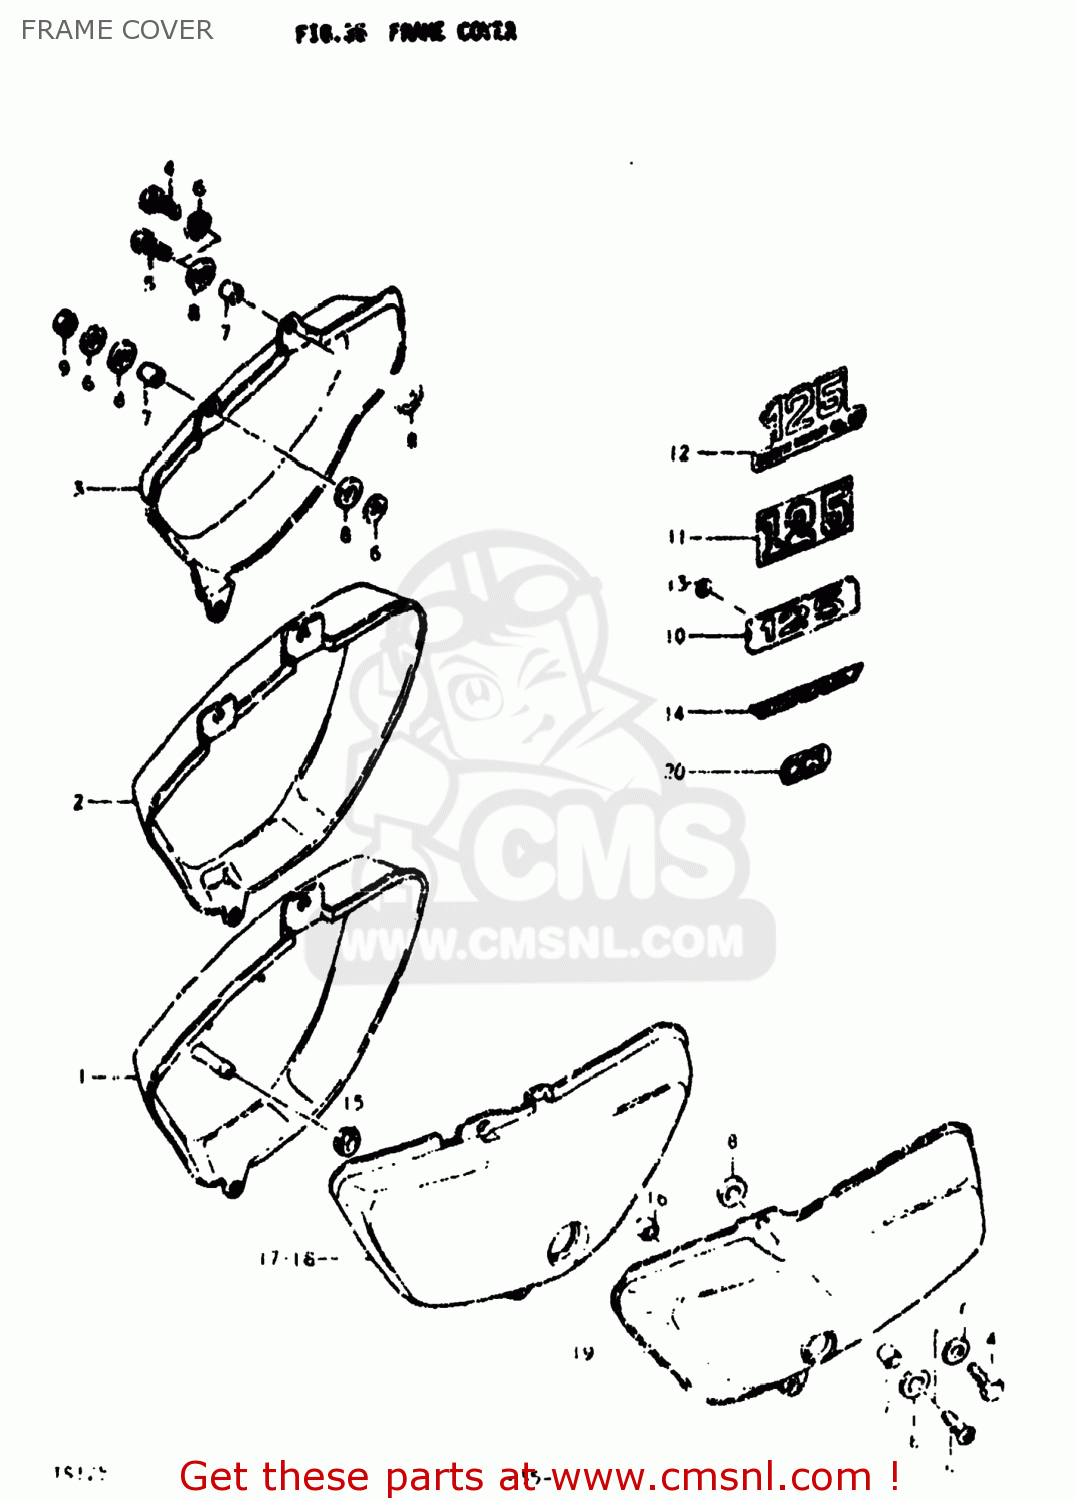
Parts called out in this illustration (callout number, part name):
1	COVER,FRAME,RIGHT
2	COVER,FRAME,RIGHT
3	COVER,FRAME,RIGHT
4	SCREW
5	SCREW
6	WASHER
7	SPACER (6.1X8X9.5)
8	CUSHION
9	NUT
10	EMBLEM,FRAME COVER
11	EMBLEM
12	EMBLEM
13	NUT
14	LABEL,COMPANY NAME
15	GROMMET
16	CUSHION
17	COVER,FRAME,LEFT
18	COVER,FRAME,LEFT
19	COVER,FRAME,LEFT
20	EMBLEM,CCIS
